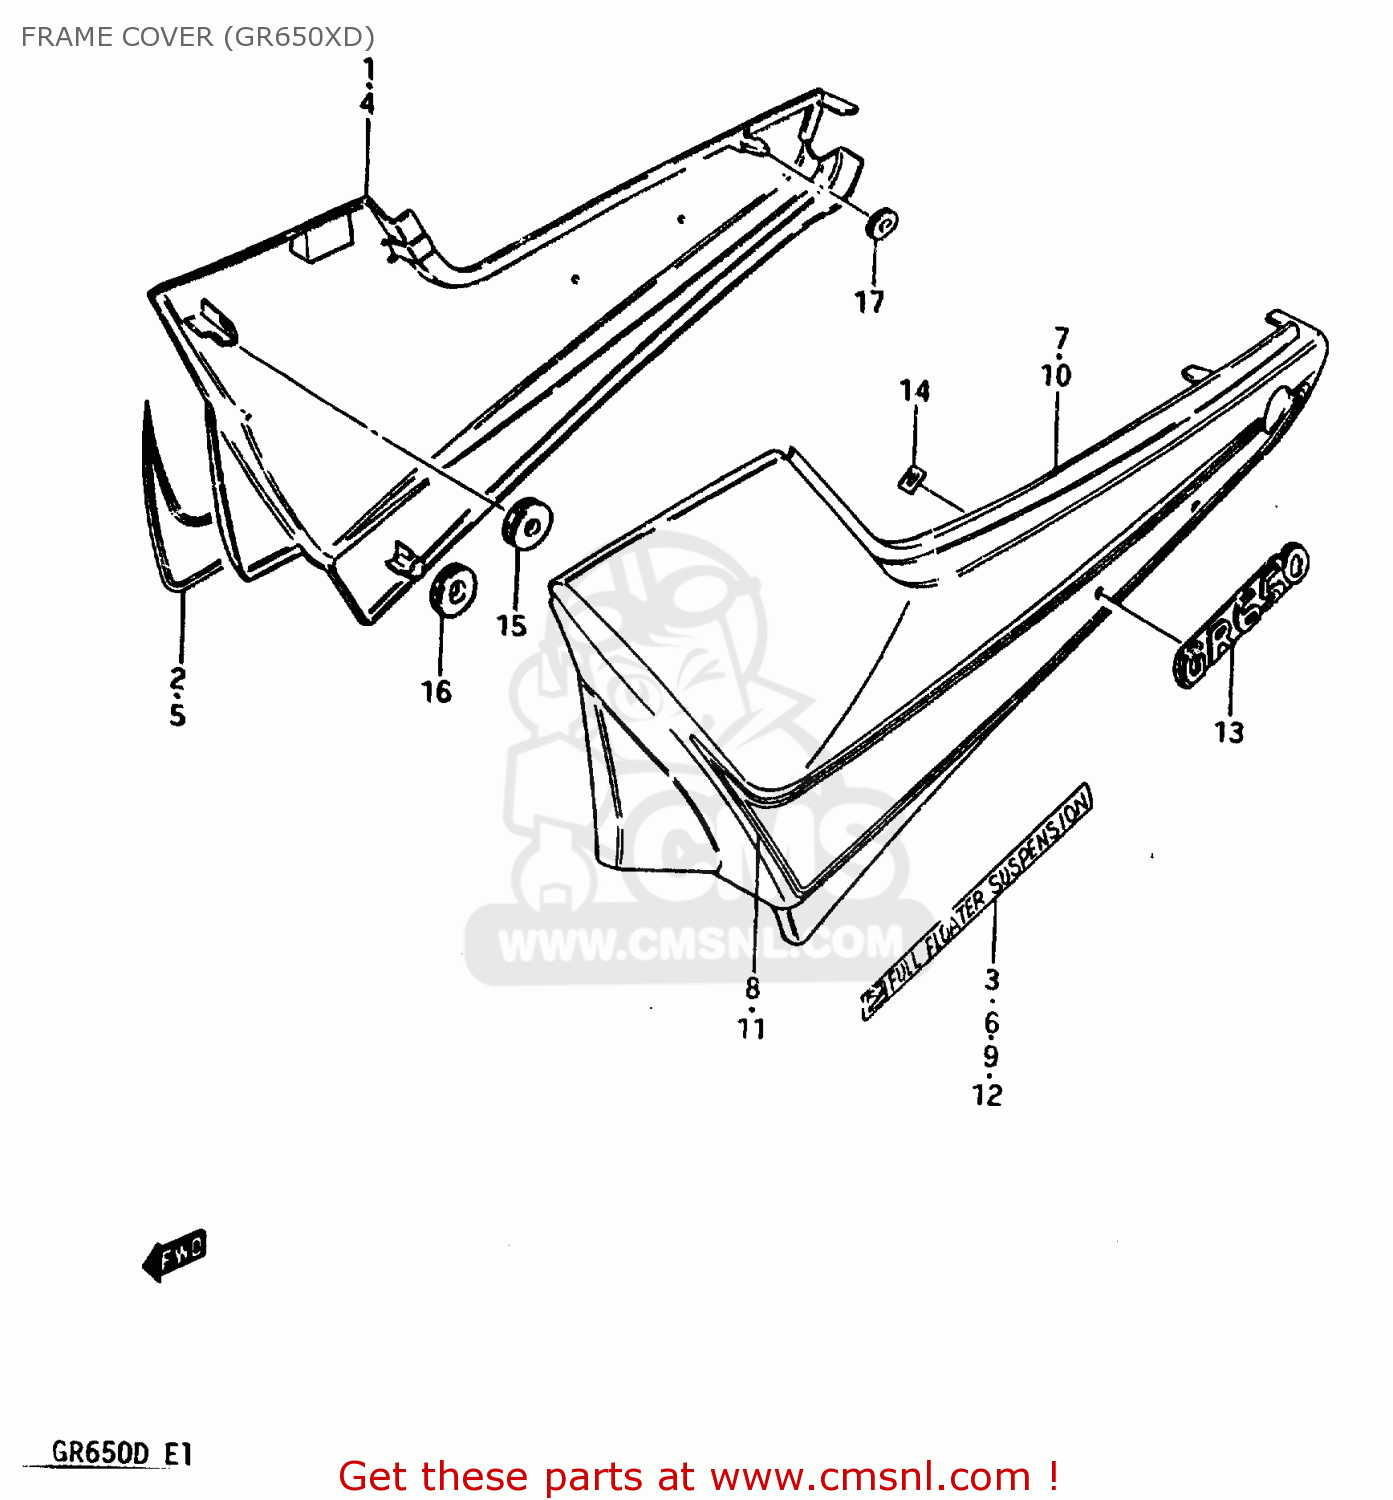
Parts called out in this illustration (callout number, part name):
1	COVER, FRAME RH (RED)
2	TAPE SET,FRAME COVER
3	EMBLEM
4	COVER, FRAME RH (BLACK)
5	TAPE SET, FRAME COVER RH
6	EMBLEM
7	COVER, FRAME LH (RED)
8	TAPE, LH
9	EMBLEM
10	COVER, FRAME LH (BLACK)
11	TAPE SET, FRAME COVER LH
12	EMBLEM
13	EMBLEM,FRAME COVER
14	NUT
15	CUSHION
16	CUSHION
17	CUSHION
